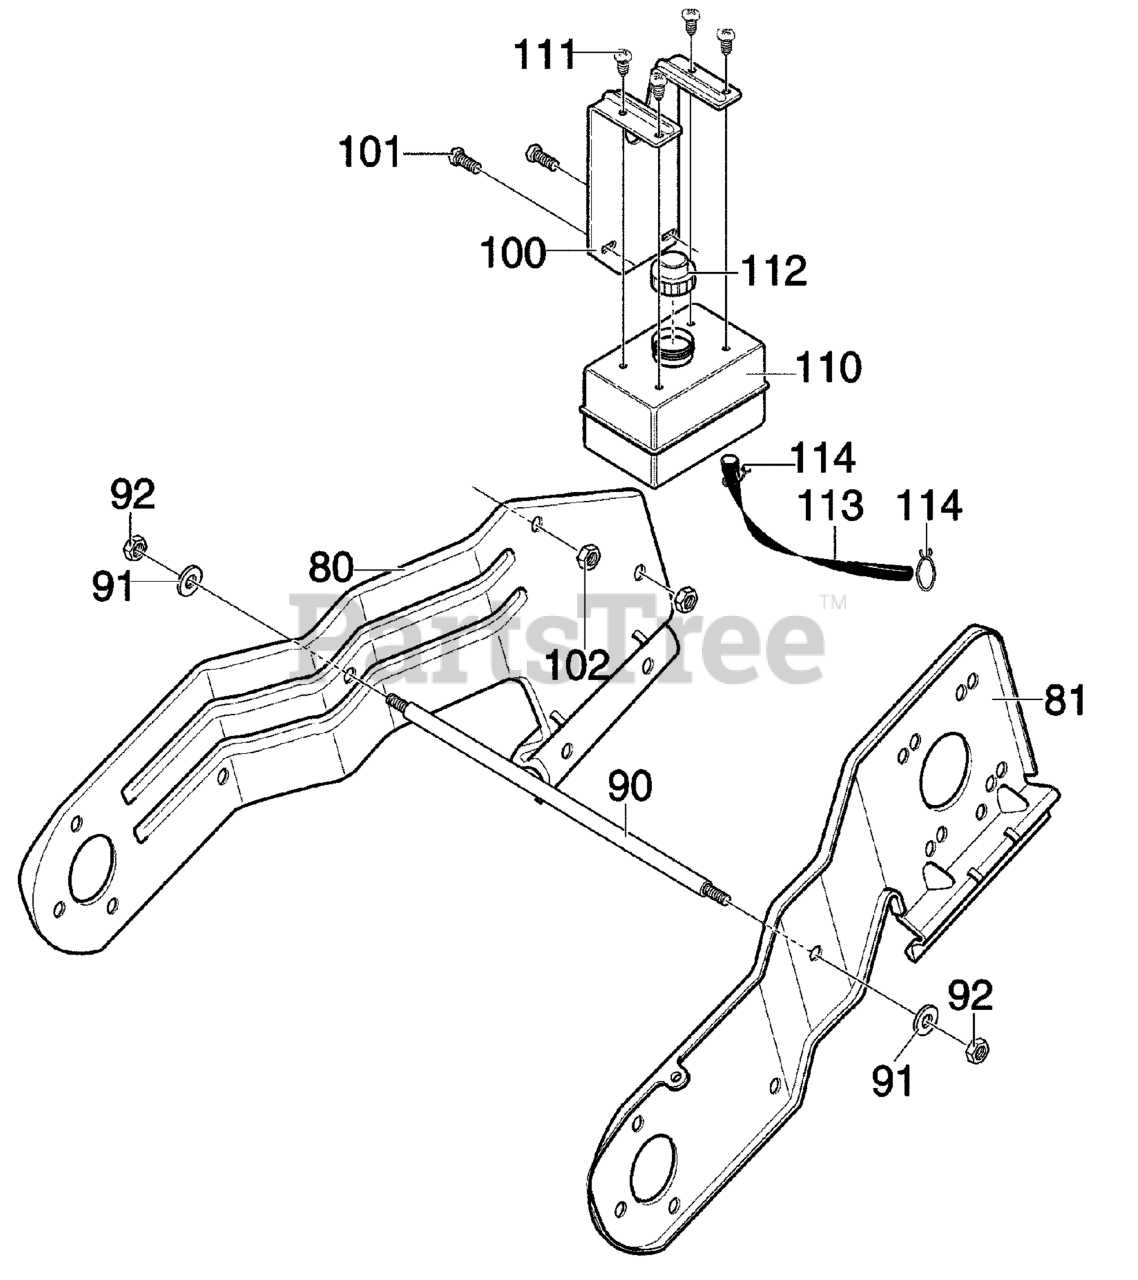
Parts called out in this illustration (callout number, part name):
80	FRAME SIDE SUPPORT RH
81	FRAME SIDE SUPPORT LH
90	ROD, SUPPORT
91	WASHER
92	NUT, 3/8-16 HEX
100	BRACKET, GAS TANK
101	SCREW, 1/4-20X.75
102	NUT, 1/4-20
110	TANK, FUEL
111	SCREW, 1/4-14X.88
112	CAP, GAS-BLACK
113	TUBING 11.50 IN.
114	CLAMP, FUEL LINE
